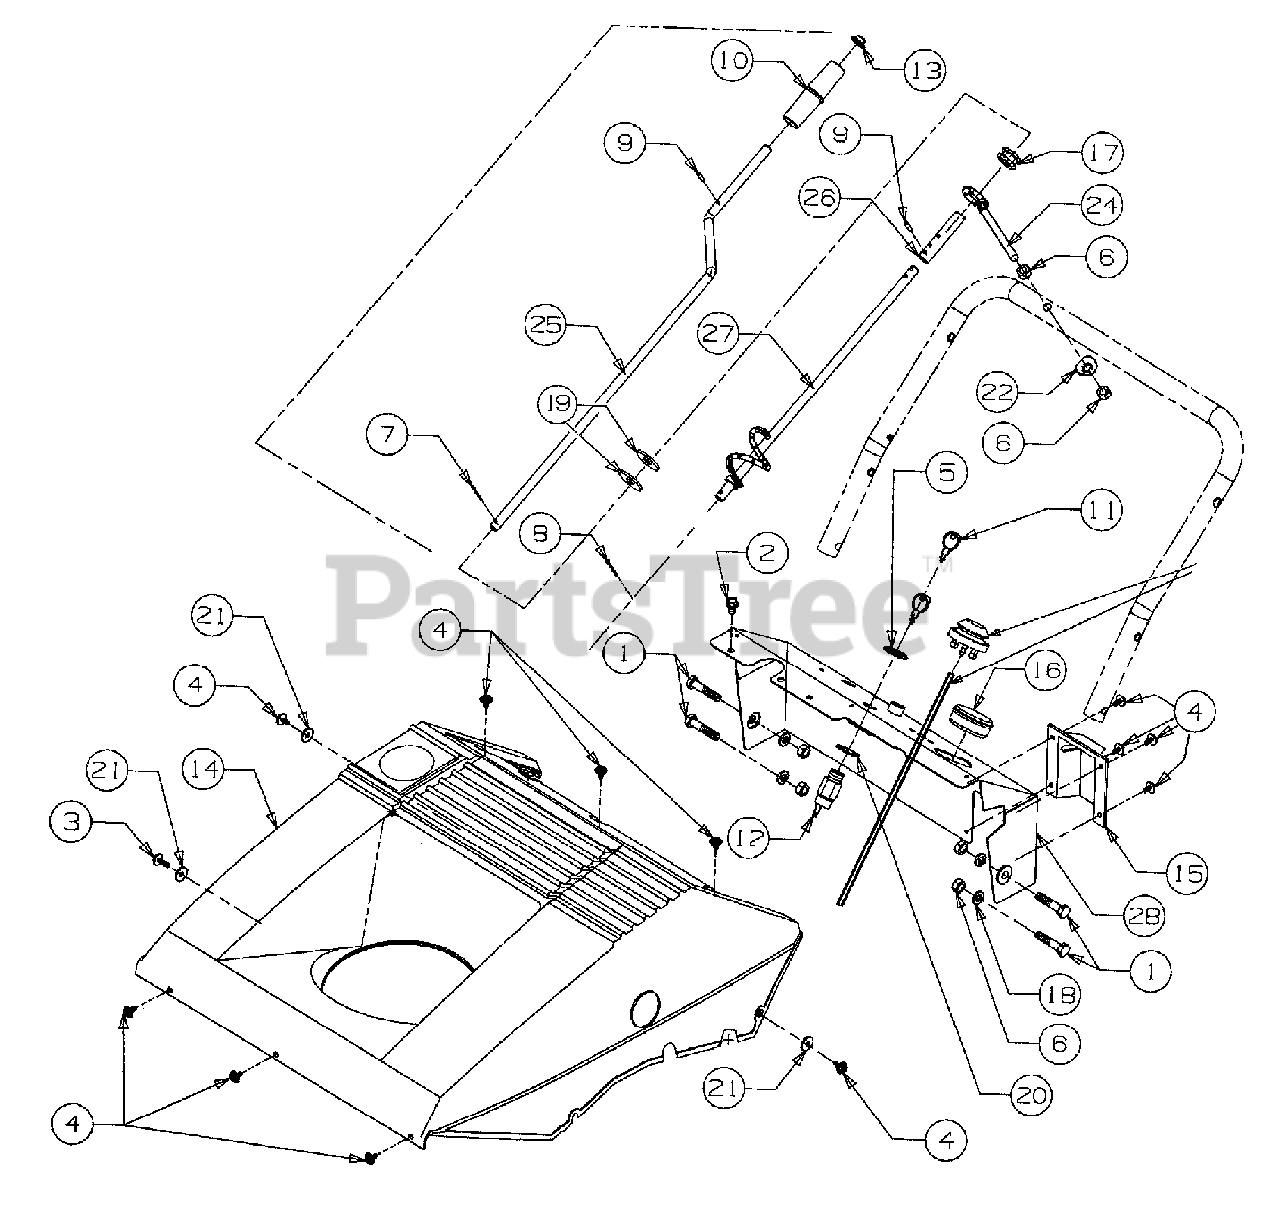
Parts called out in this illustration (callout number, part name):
1	Screw-Hex
2	Screw-Hex Washer
3	Screw-Hex
4	Screw-Hex
5	Nut-Jam
6	Nut-Hex
7	Pin-Cotter
8	Pin-Cotter
9	Pin Roll
11	Key-Ignition
12	Switch
13	Cap-Push
14	Shroud-Black
15	Cover-Choke
16	Plug-Insert
17	Grommet-Rubber
18	Washer-Lock
20	Washer-Lock-Internal
21	Washer-Flat
22	Washer-Saddle
24	Eyebolt-Chute Crank
26	Spacer
27	Crank-Chute 13.5" Lg.
